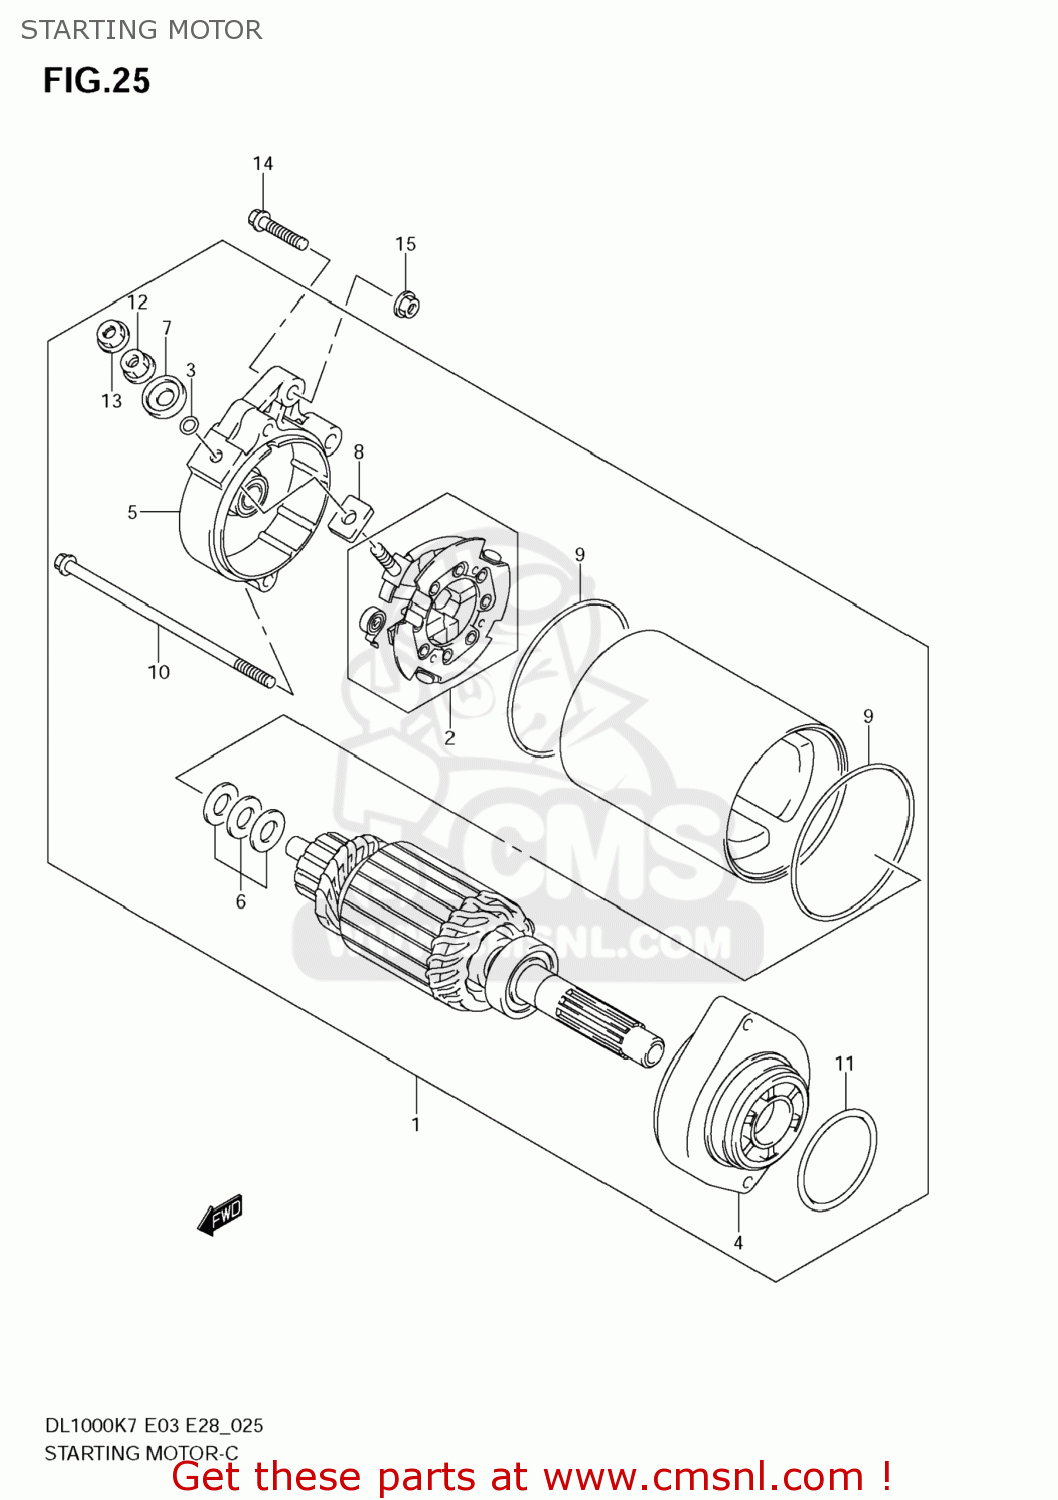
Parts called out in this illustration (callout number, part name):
1	MOTOR ASSY,STARTING
2	HOLDER SET,BRUSH
3	O RING
4	HOUSING ASSY
5	FRAME ASSY
6	SHIM SET,STARTING MOTOR
7	BUSHING
8	BUSHING
9	O RING
10	BOLT
11	O RING
12	NUT
13	NUT
14	BOLT(6X25)
15	NUT
